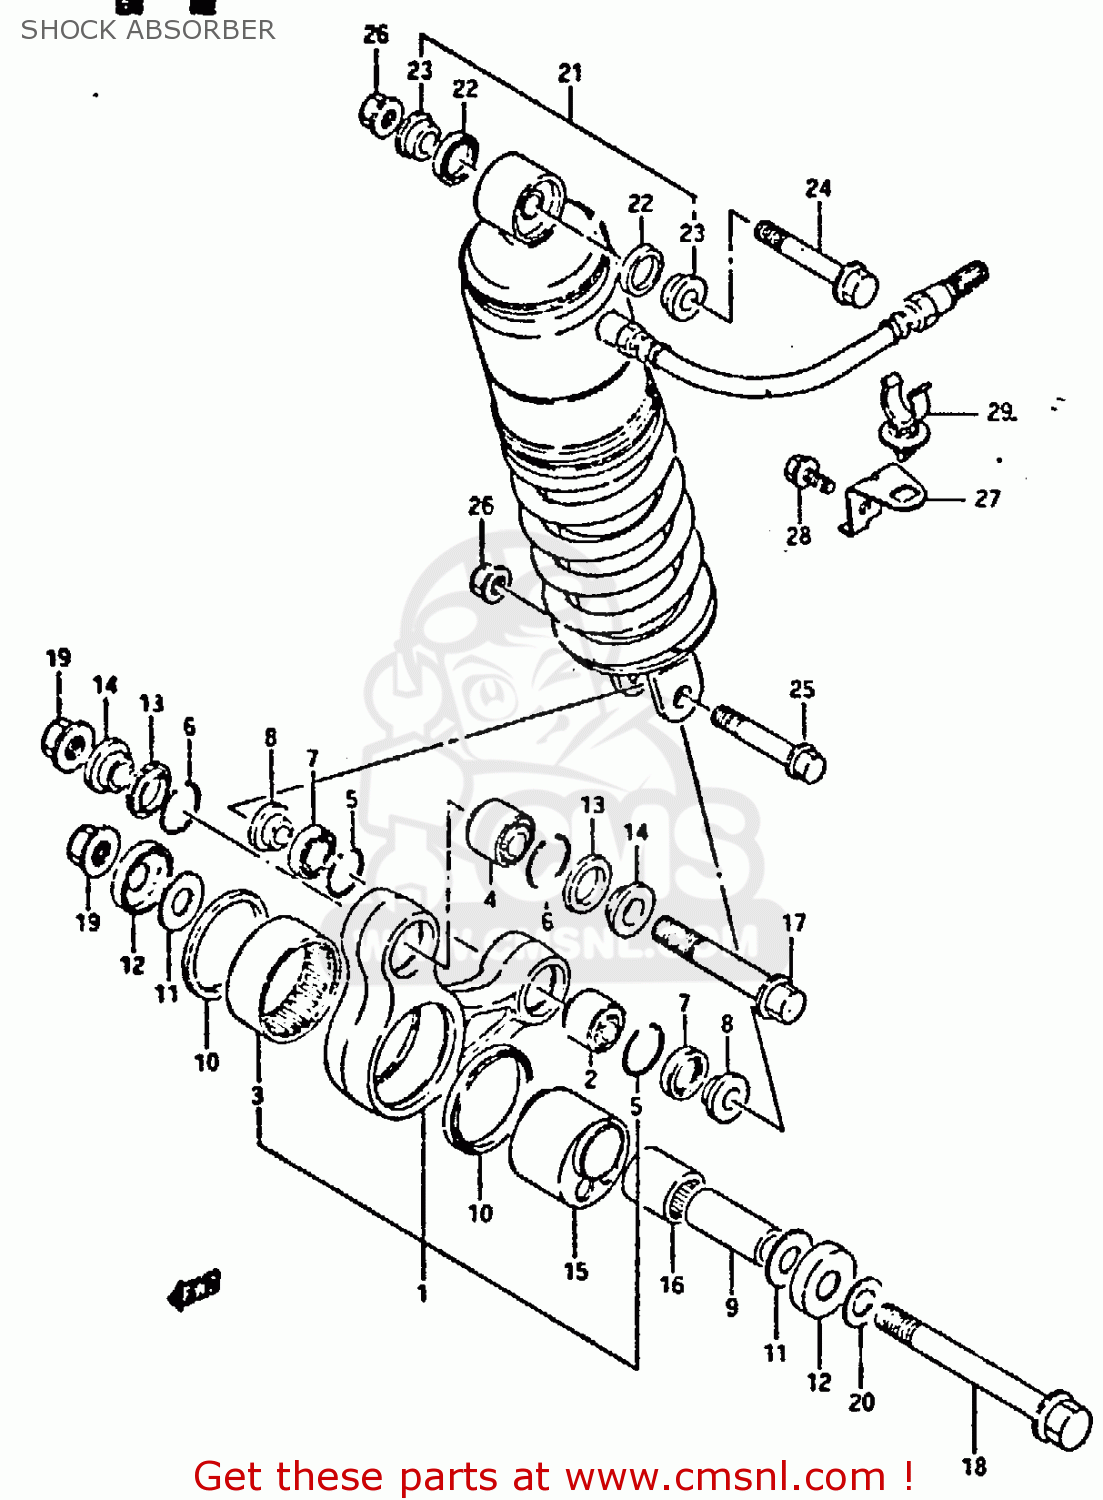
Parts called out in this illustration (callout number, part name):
2	BEARING
3	BEARING(45X52X20)
4	BEARING(12X26X16)
5	RING,STOPPER
6	RING,STOPPER
7	DUST SEAL,RR CUSHION LEVER RR
8	SPACER
9	SPACER,ECCENTRIC LVR CTR
10	SEAL,ECCENTRIC LVR DUST CTR
11	WASHER
12	COVER,REAR SWING ARM DUST
13	SEAL,RR CUSHION ROD DUST
14	SPACER
15	ECCENTRIC SPACER,REAR SUSPENSION
16	ROLLER BEARING (17X24X25)
17	BOLT,RR CUSHION LEVER FR
18	BOLT(12X105)
19	NUT 12MM
20	SHIM
22	DUST SEAL
23	SPACER
24	BOLT(10X58)
25	BOLT(10X52)
26	NUT
28	BOLT
29	CLAMP
